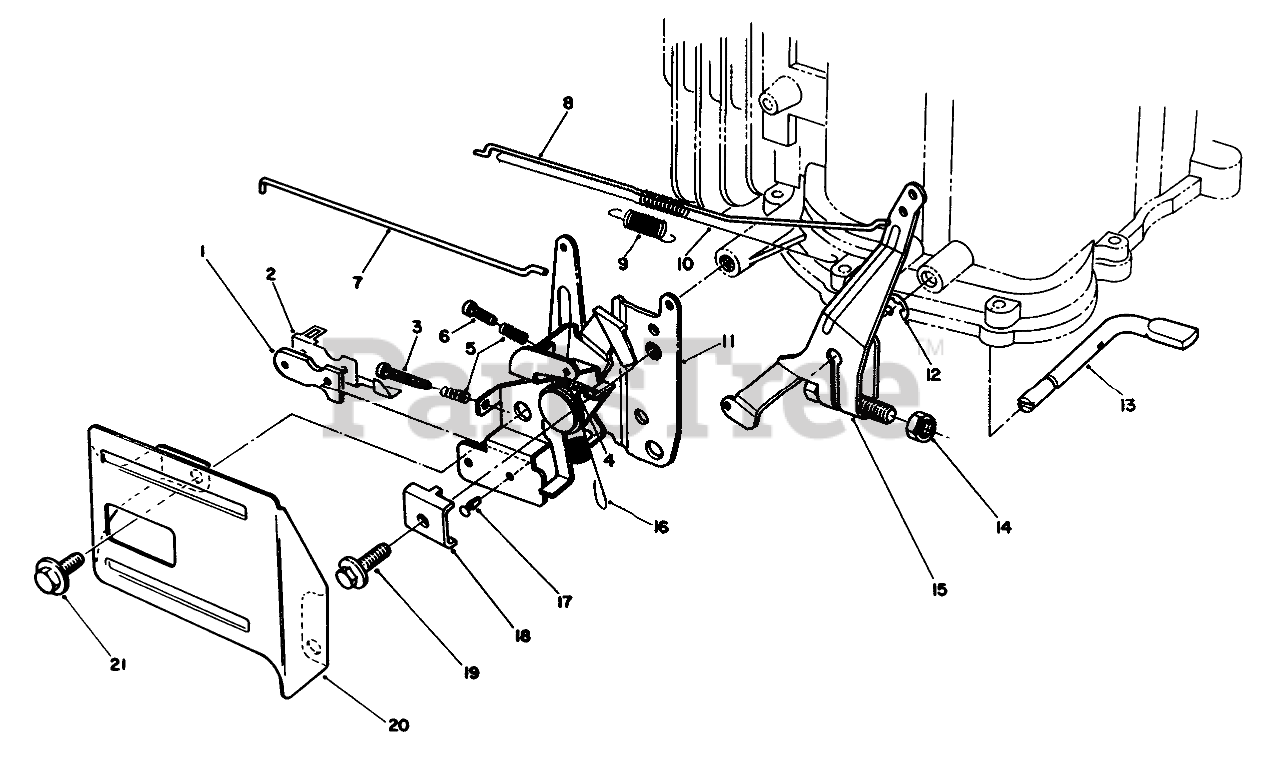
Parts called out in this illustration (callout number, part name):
1	INSULATOR-KILL SWITCH
2	TERMINAL-KILL SWITCH
3	SCREW
4	Spring
5	SPRING
6	SCREW
7	Rod-Choke
8	Rod-Carburetor
9	SPRING
10	SPRING
11	THROTTLE
12	E-RING
13	SHAFT
15	ARM ASM
16	SPRING
17	RIVET
18	CLAMP-CABLE
20	THROTTLE GUARD
